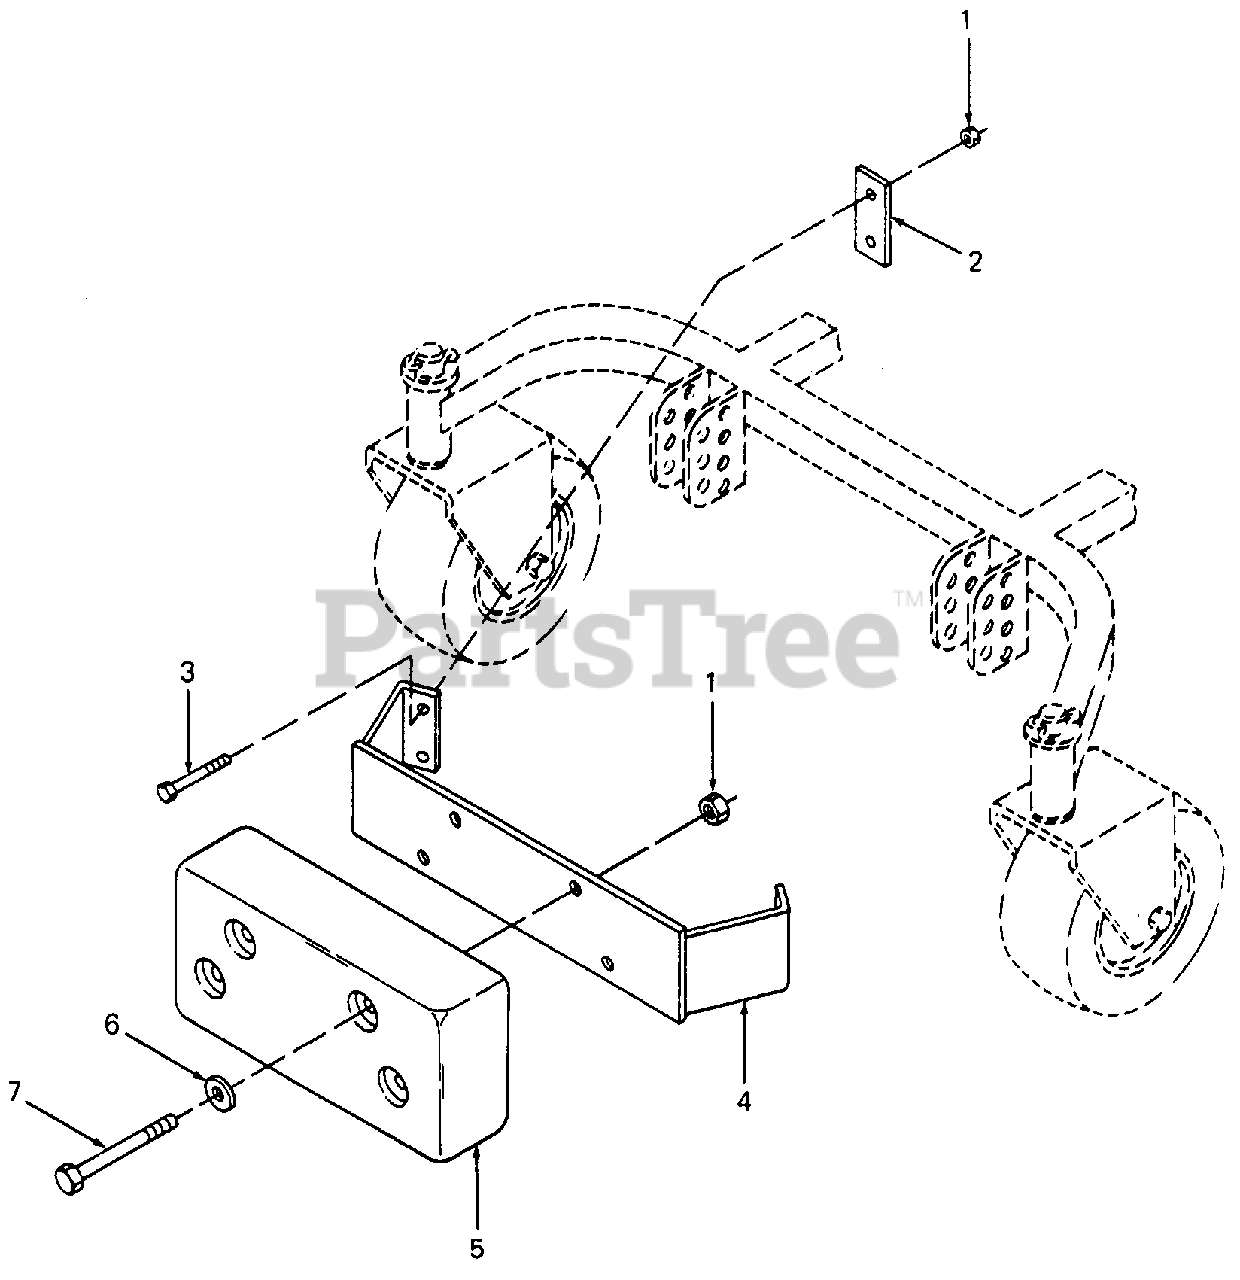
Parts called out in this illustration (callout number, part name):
1	Nut, Lock, 1/2-13
2	Strap, Weight Rack
3	Bolt, Hex, 1/2-13 X 2-3/4
4	Weldment, Weight Rack
5	Weight, Front Counter
6	Washer, Flat, 1/2
7	Bolt, Hex, 1/2-13 X 5
